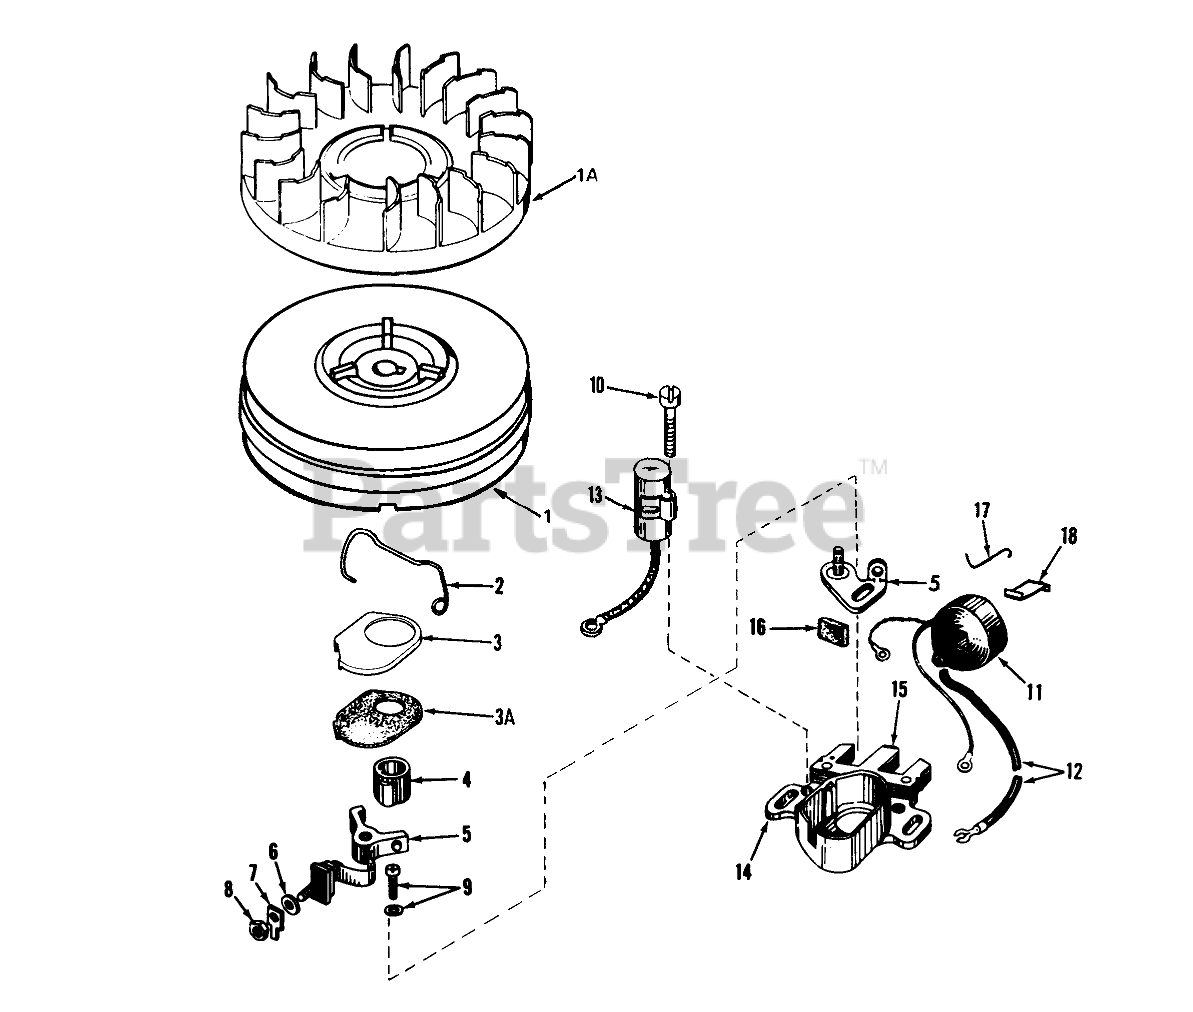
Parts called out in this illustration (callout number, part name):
1	Flywheel (Incl.Nos.1A, 3 & 3A)
2	Spring Breaker Box
3	Cover-Dust
3A	Gasket, Dust Cover
4	Cam, Breaker
5	Breaker Assy.
7	Terminal, Ground
9	Breaker Screw
10	Condenser Screw
11	Coil Assy. (Incl.No.12)
12	Wire, Lead
13	Condenser
14	Core & Plate
15	Stator Assy. (Incl.Nos.2, 3, 3A, 5 thru 14& 16 thru 18)
16	Felt,Cam Wiper
17	Clip, Coil
18	Spring Coil Wedge
